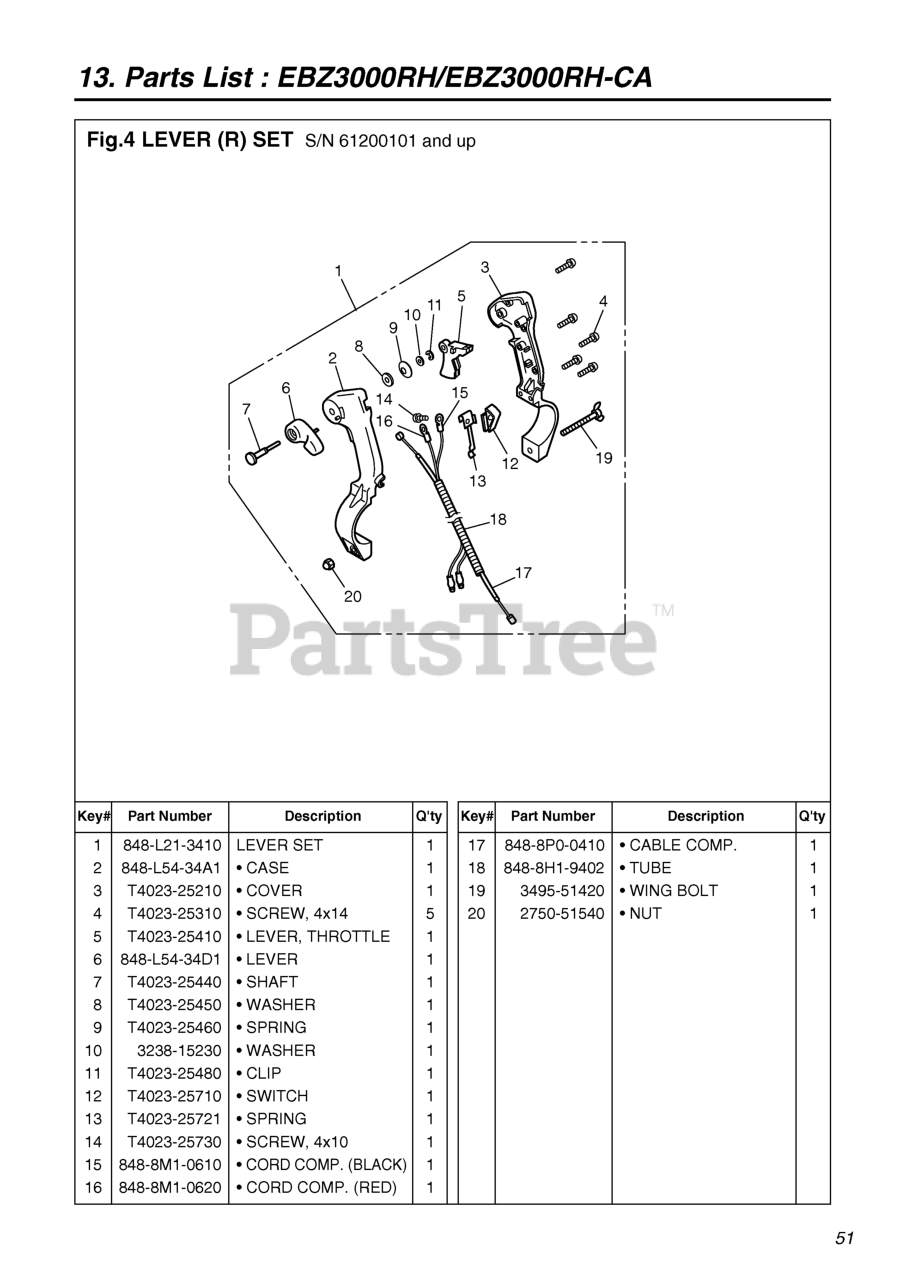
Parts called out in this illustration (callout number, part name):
1	LEVER SET
2	CASE
3	USE T402325211
4	SCREW 4X14
5	LEVER, THROTTLE
6	LEVER
7	SHAFT
8	WASHER
9	SPRING WASHER
10	WASHER
11	CLIP
12	SWITCH
13	SPRING
14	SCREW 4X10
15	CORD COMP-BLK
16	CORD COMP-RED
17	CABLE COMP
18	TUBE
19	BOLT, WING
20	NUT
